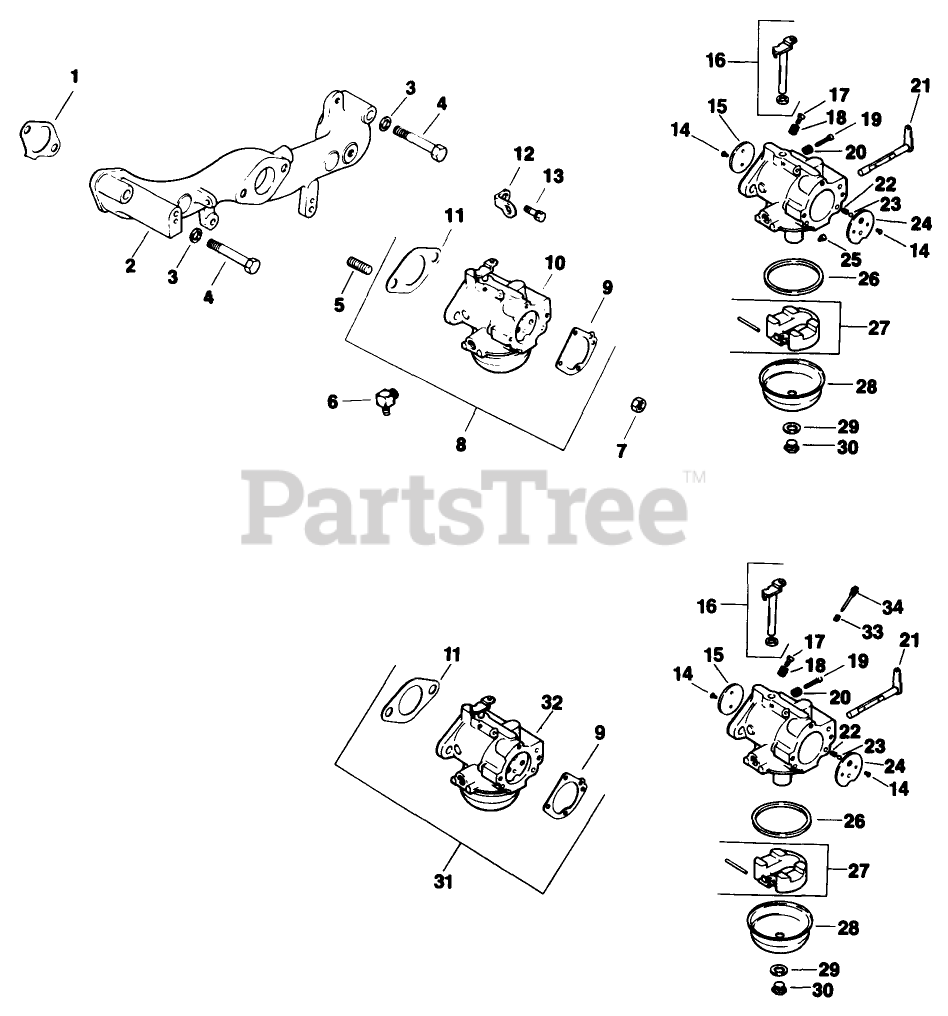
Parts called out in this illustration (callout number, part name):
1	Gasket-Intake
2	Manifold-Intake
3	Washer
4	Screw
6	Connector-Hose
8	Carburetor Kit w/Linkage (Incl. Ref. #7-9,14-30)
9	Gasket-Elbow
10	Carburetor Assembly Ref.
11	Gasket
12	Strap Lifting
13	Screw
14	Screw-Throttle Plate (Only On: 72042,72043,72062,72063)
15	Plate-Throttle
16	Shaft Assembly
17	Needle-Idle Fuel Adj.
19	Screw-Idle Speed Adj.
20	Spring-Idle Speed
21	Lever-Choke
22	Spring-Choke Friction
23	Ball-Choke Friction
24	Plate-Choke
25	Jet-Main
26	Gasket
27	Kit-Float
28	Bowl-Fuel
29	Gasket-Retainer Screw
30	Screw-Bowl Retainer
31	Kit-Carburetor w/Gasket
32	CARburetor Assembly For Information Only
34	Needle-Main Fuel
